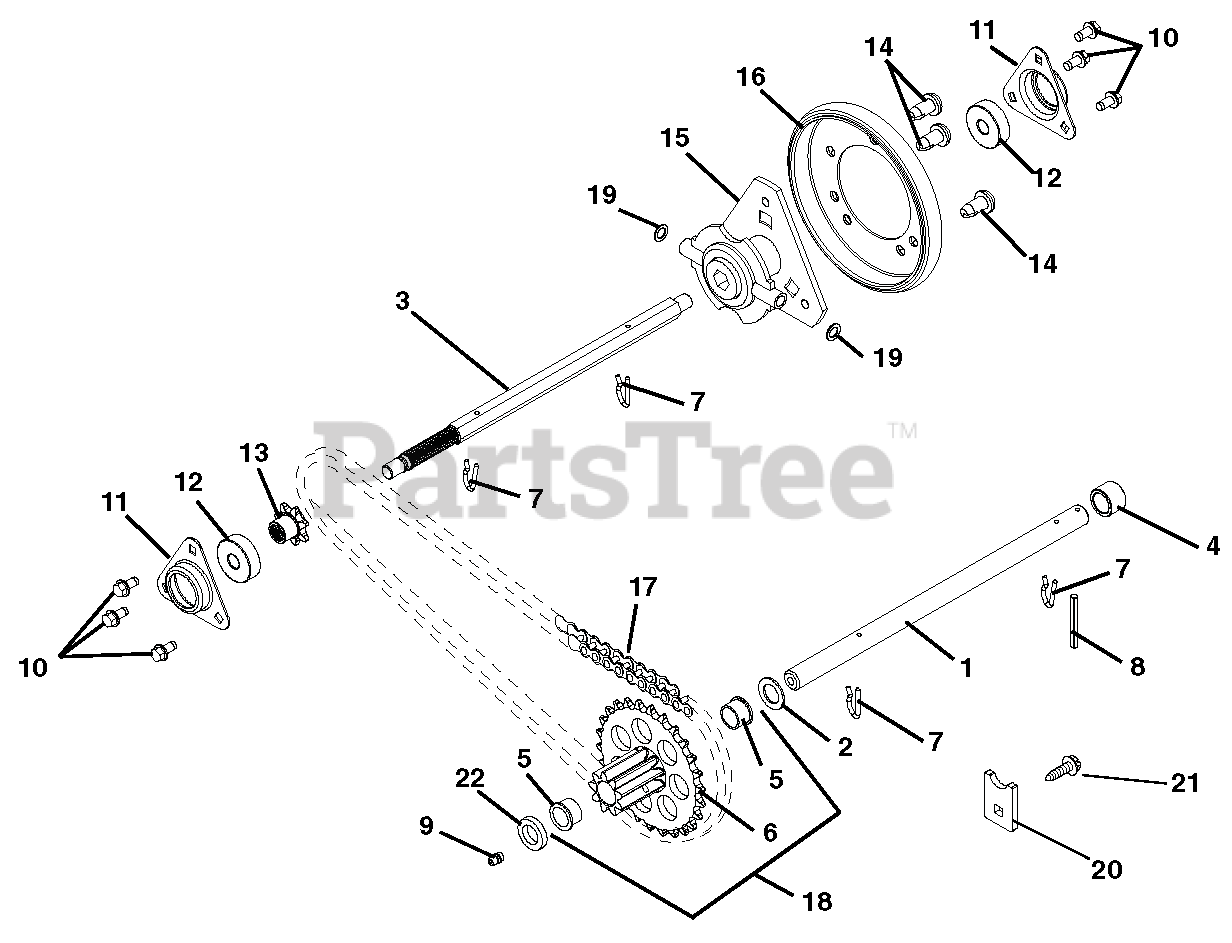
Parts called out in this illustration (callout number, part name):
1	SHAFT, PINION
2	WSHR-FL-STL .630X1.005X.062 YZ
3	SHAFT, HEX-W/SPLINE
4	SPACER, .635X.880X.611
5	BSHG-FLG .625X.750X.500X.875
6	PINION & SPROCKET
7	PIN, SPRING CLIP
8	PIN-ROLL .125X1.00
9	ZERK,FITTING .25X.125 DRIVE IN
10	@SCR-TAP .25-20X.50 HWH TR YWZ
11	FLANGE, BEARING
12	BRG-BALL .437X1.375X.437
13	SPROCKET, PINION 7T W/SPLINE
14	SCR-TAP SERRDHDTX .31-18X.50BP
15	CARRIER, DRIVE DISK
16	FRICTION, DISC
17	CHAIN - #41, 32 PITCHES
18	PINION & SPROCKET W/BUSHINGS
19	WSHR-FL-STL .505X1.00X.062YWZC
20	TAB, ANTI ROTATION
21	@SCR-TAP .25-20X.50 HWH TR YWZ
22	BSHG-SLV, .635X.880X.305
